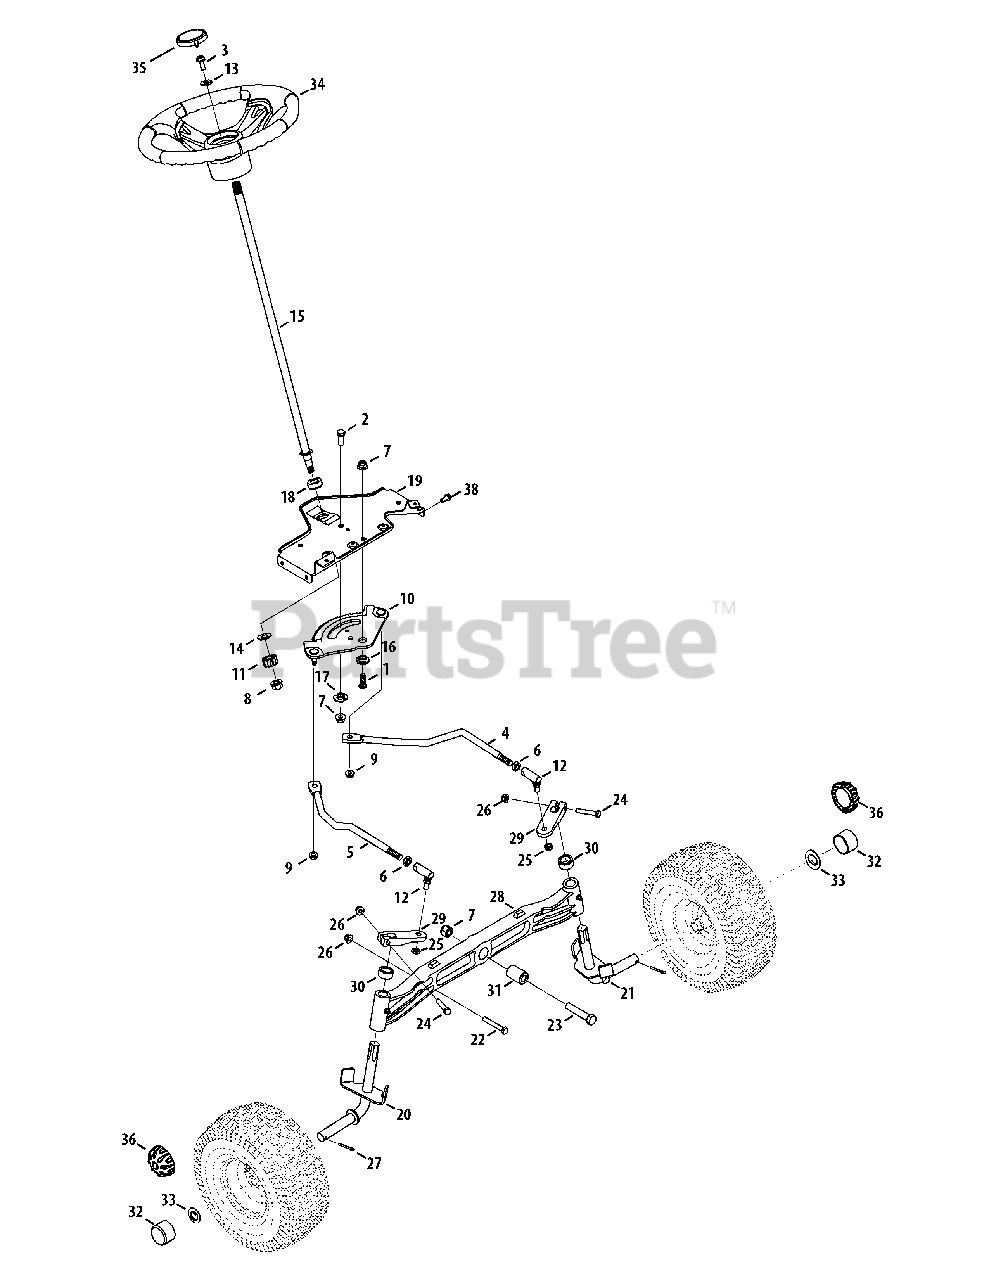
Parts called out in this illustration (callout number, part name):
1	Screw, 3/8-16 x 1.0
2	Hex Screw 3/16 x 1.00
3	Hex Screw 5/16-18 x 1.00 Special
4	Link, Drag LH
5	Link, Drag RH
6	Hex Jam Nut 7/16-20
7	Flange Lock-Nut 3/8-16 Gr. F Nylon
8	Flange Lock Nut, 7/16-20
9	Hex Flange L-Nut 5/16-18
10	Steering Gear, 11/90 Ratio
11	Steering Pinion Gear
12	Ball Joint, 7/16 - 20
13	Flat Washer .406 ID x .875 DE x .105
14	Fl. Washer .510 x 1.120 x .060
15	Steering Shaft .625 OD x 24.25
16	Shoulder Spacer .385 x 1.25 x .3025
17	Shoulder Spacer .385 x 1.25 x .3025
18	Hex Flange Bearing 5/8
22	Hex Bolt 5/16-18 x 2.25
23	Hex Cap Screw, 3/8-16 x 2.5
24	Hex Screw 5/16-18 x 1.75" Lg.
25	Hex Cent L-Nut 3/8-24
26	Flange Locknut 5/16-18 Gr. F, Nylon
27	Cotter Pin 5/32" Dia.
28	Pivot Bar (cast)
29	Steering Block
30	Spacer .710 ID x .125 OD x .56
31	Spacer .385 x 1.0 x 1.5075
32	Hub Cap
33	Flat Washer .350 x 1.559 x .062
34	Steering Wheel, Standard Grip
35	Steering Wheel Cap (spig) logo
36	Hub Cap
38	S-Tapp Screw. 5/16-18 x .75
